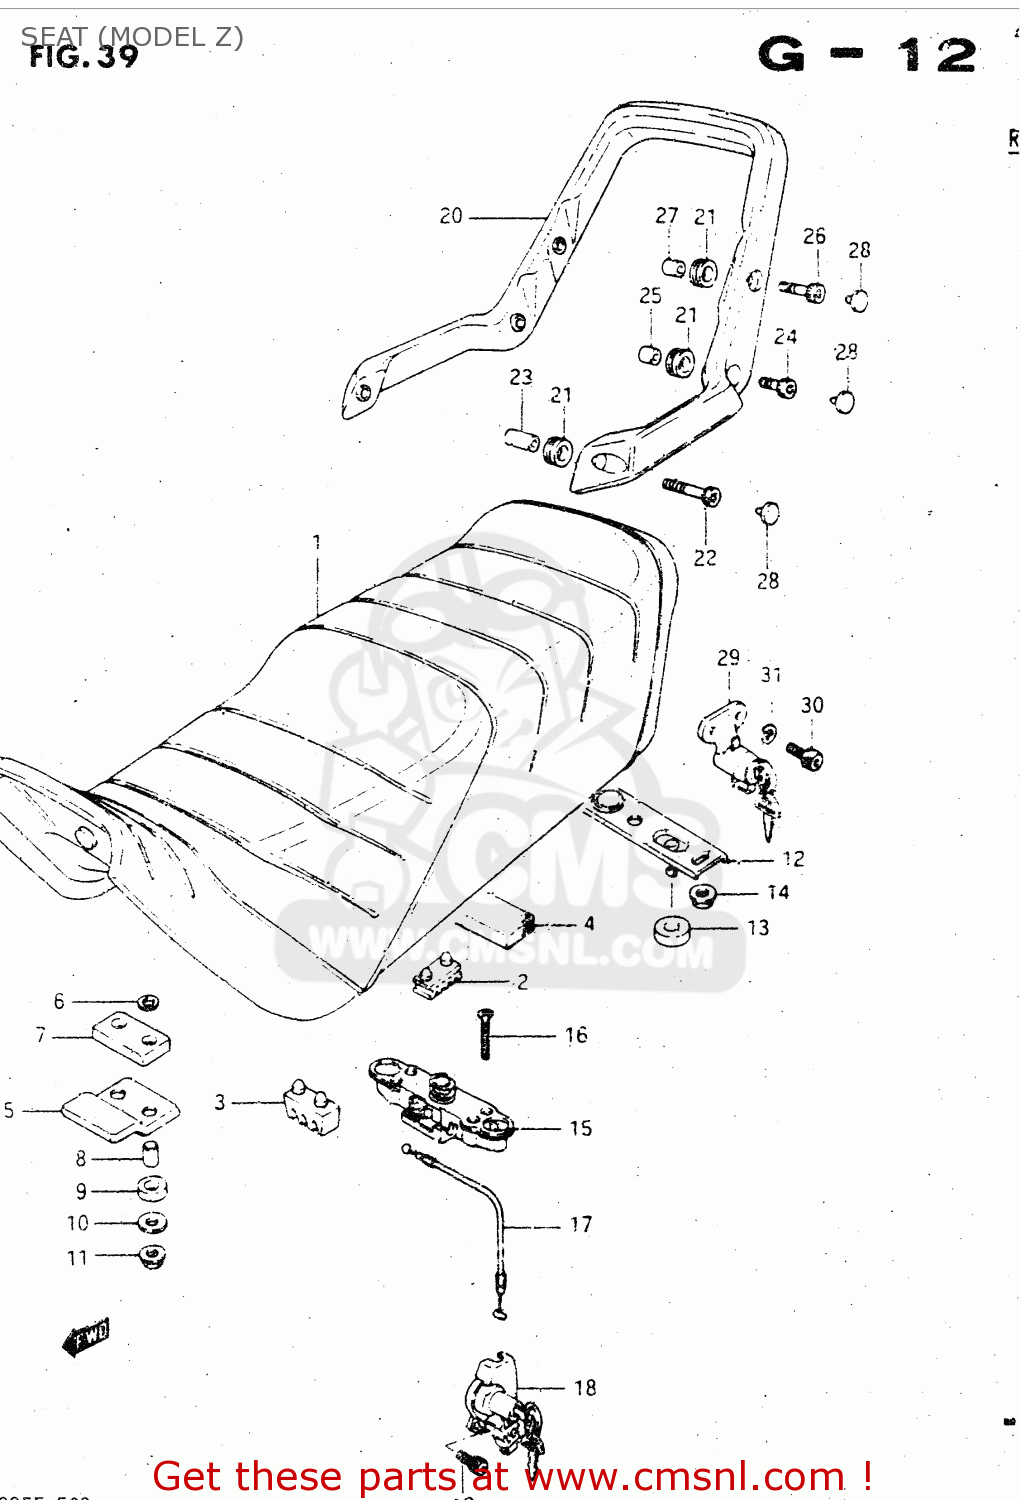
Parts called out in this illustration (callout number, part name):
1	SEAT ASSEMBLY
2	CUSHION,SEAT(40X20X15)
3	CUSHION,SUPPORT(50X25X32)
4	CUSHION(30X60X10)
5	PLATE,SEAT HOOK,FRONT
6	WASHER
7	CUSHION,SEAT
8	SPACER (6.1X8X12)
9	CUSHION
10	WASHER
11	NUT
12	STRIKER, SEAT LOCK
13	CUSHION,STRIKER
14	NUT
15	LOCK ASSY,SEAT STRIKER
16	SCREW,6X30
17	CABLE,SEAT LOCK
18	LOCK ASSEMBLY,SEAT & HELMET
19	BOLT
20	HANDLE,PILLION RIDER
21	GROMMET,PILION RIDER HANDLE
22	BOLT
23	SPACER,PILLION RIDER HOLDER
24	BOLT
25	SPACER,PILLION RIDER HOLDER
26	BOLT
27	SPACER,PILLION RIDER HOLDER
28	CAP(OD:10)
29	LOCK ASSEMBLY,HELMET
30	BOLT
31	WASHER,LOCK
